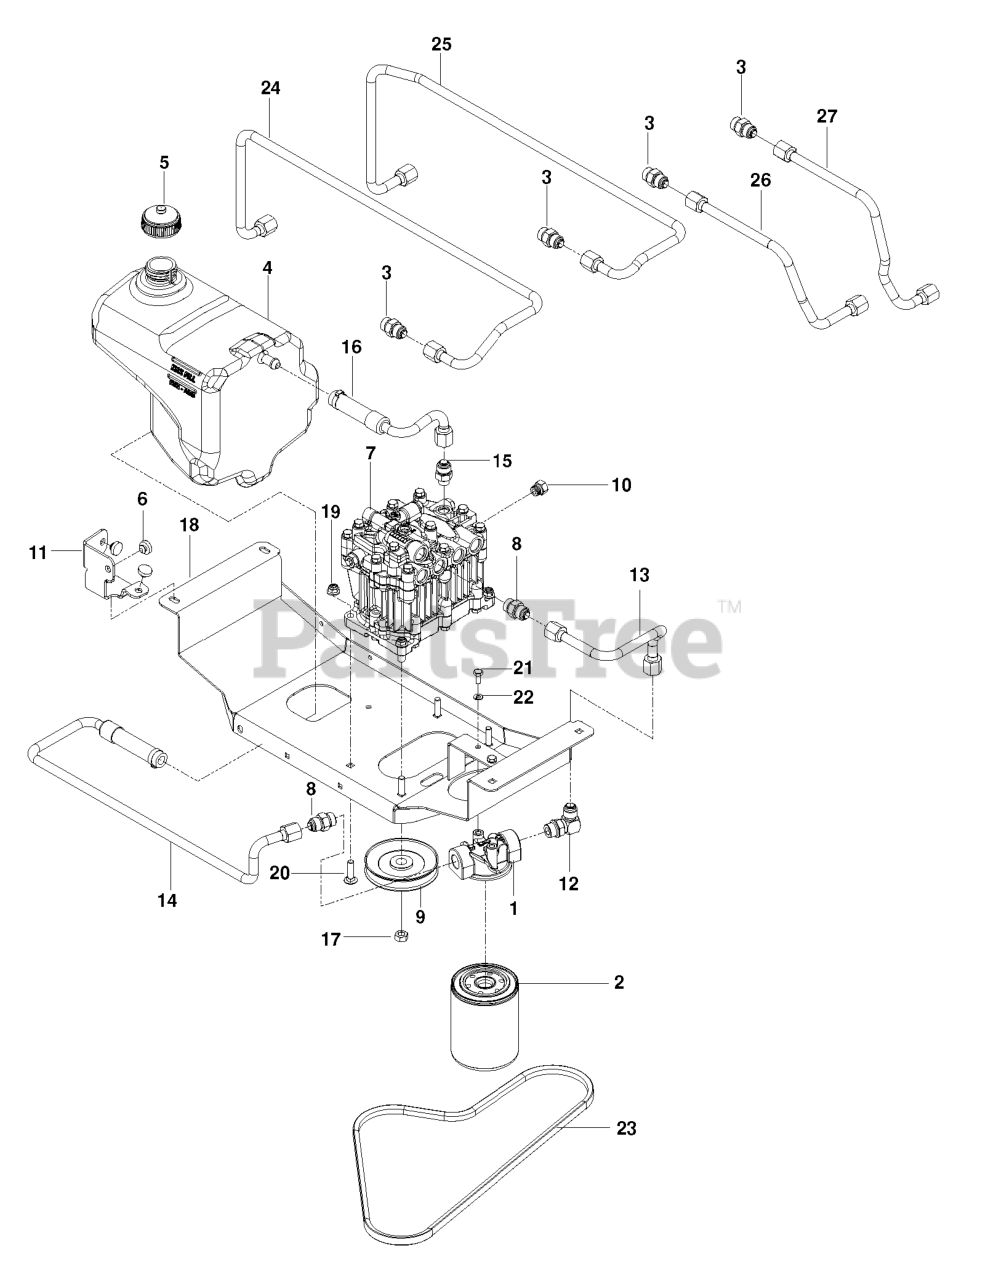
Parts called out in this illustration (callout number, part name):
1	FILTER HEAD
2	HYDRAULIC OIL FILTER
3	FITTING, STRAIGHT F6400-8-8-0
4	RESERVOIR HYDRO
5	HYDRAULIC CAP
6	GROMMET, BUMPER
7	PUMP, DUP10S (77808041201)
8	FITTING, 10-8 STRAIGHT
9	PULLEY, PUMP
10	PLUG, 6408-6
11	SUPPORT, RESERVOIR
12	FITTING, 10-8 90 DEG
13	HYD LINE, CHARGE
14	HYD LINE, INLET
15	FITTING, HYDRO
16	HYDRO LINE, CASE
17	NUT M10-1.5 L/H HEX
18	PLATE, PUMP
19	5/16-18 NYLOC FLANGE NUT
20	BOLT, CARRIAGE 5/16X1-1/4
21	HCS 1/4C X 5/8
22	LOCKWASHER 1/4"
24	HYDRO LINE, A
25	HYDRO LINE, B
26	HYDRO LINE, C
27	HYDRO LINE, D
